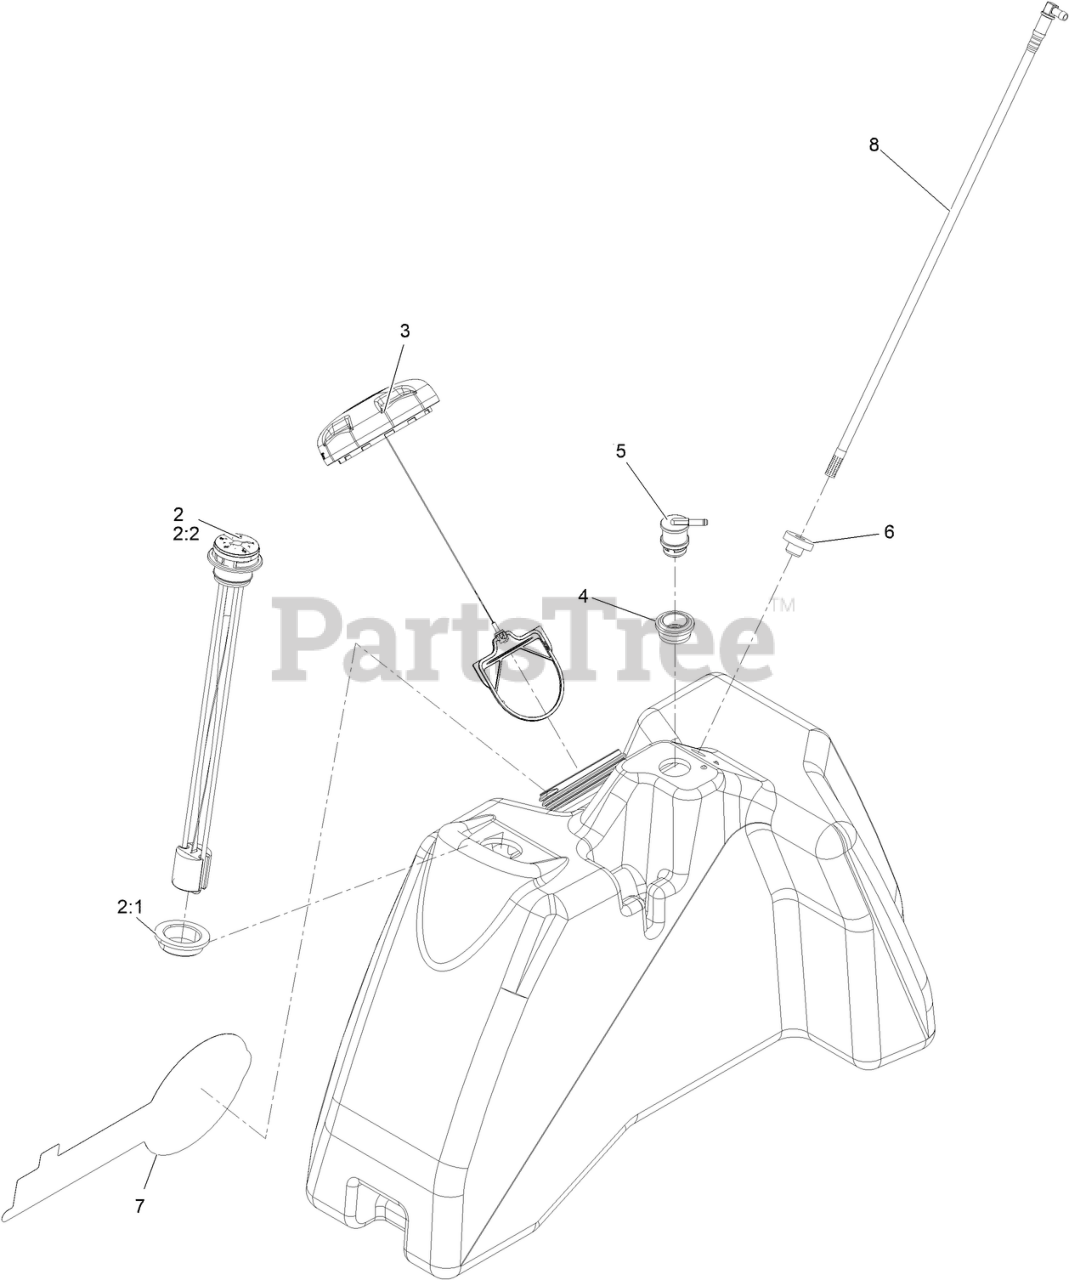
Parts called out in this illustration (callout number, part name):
2	Gauge ASM-Fuel
2:2	Dial-Gauge
3	CAP-FUEL, RATCHETING
4	GROMMET
5	VALVE-VENT, FUEL
6	BUSHING
7	DECAL-EXMARK LOGO FUEL
8	STAND PIPE
